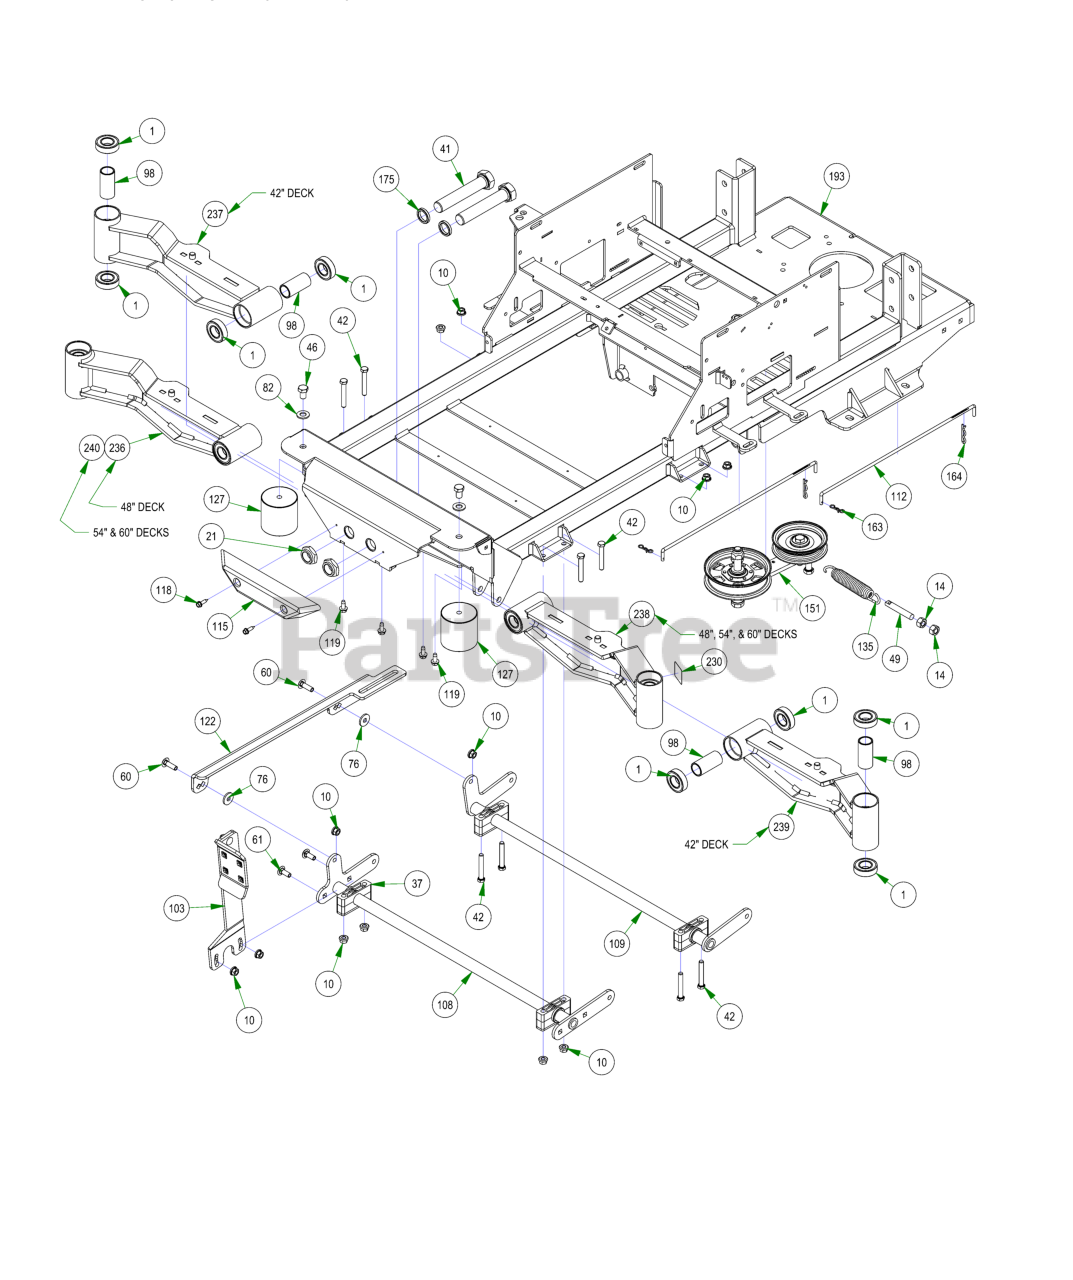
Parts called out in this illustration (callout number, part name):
1	1641 BEARING W/2 CONTACT RUBBER SEALS
10	3/8-16 NYLON INSERT FLANGE LOCKNUT (GR.F) ZINC
14	1/2-13 HEX NUT ZINC
21	1"-14 NYLON INSERT JAM LOCKNUT ZINC
37	Pillow Block Kit
41	1"-14 X 5-1/2 HEX CAP SCREW (GR.8) ZINC YELLOW
42	3/8-16 X 2-1/2 HEX CAP SCREW (GR.5) ZINC
46	1/2-13 X 3/4 HEX CAP SCREW (GR.5) ZINC
49	All Thread
60	3/8-16 X 1-1/4 CARRIAGE BOLT ZINC
61	3/8-16 X 1 CARRIAGE BOLT (GR.5) ZINC
76	.390 ID X 1.12 OD X .125 THK FLAT WASHER NYLON
82	1/2 SAE FLAT WASHER (1-1/16" OD) GR.8 ZINC YELLOW
98	2016 Front Bearing Spacer
103	Foot Pedal Assembly
108	Actuator Bar Front- 2017 MZ/ZT
109	Actuator Bar Rear- 2017 MZ/ZT
112	Neutral Rod
115	Bumper EZT
118	1/4 x 1 Hex Head Tek Screw
119	5/16-18 X 3/4 HEX WASHER SLOT (F) TCS ZINC
122	2017 MZ/ZT Actuator Linkage
127	Vibration Mount- Red Dot
135	Deck Idler Spring
151	Maverick Pump Idler
164	Neutral Rod Clip
175	Spacer, 1x1.375x.25
193	2022 Maverick Frame - Painted
230	Independetly Articulating Front Suspension Arms Patent Decal
236	2021 Maverick RH Short Front Suspension Arm Assy (48")
237	2022 42" Maverick I-Beam Front Arm - RH - Painted
238	2021 Maverick LH Front Suspension Arm Assy (48", 54" & 60")
239	2022 42" Maverick I-Beam Front Arm - LH - Painted
240	2021 Maverick RH Long Front Suspension Arm Assy (54" & 60")
